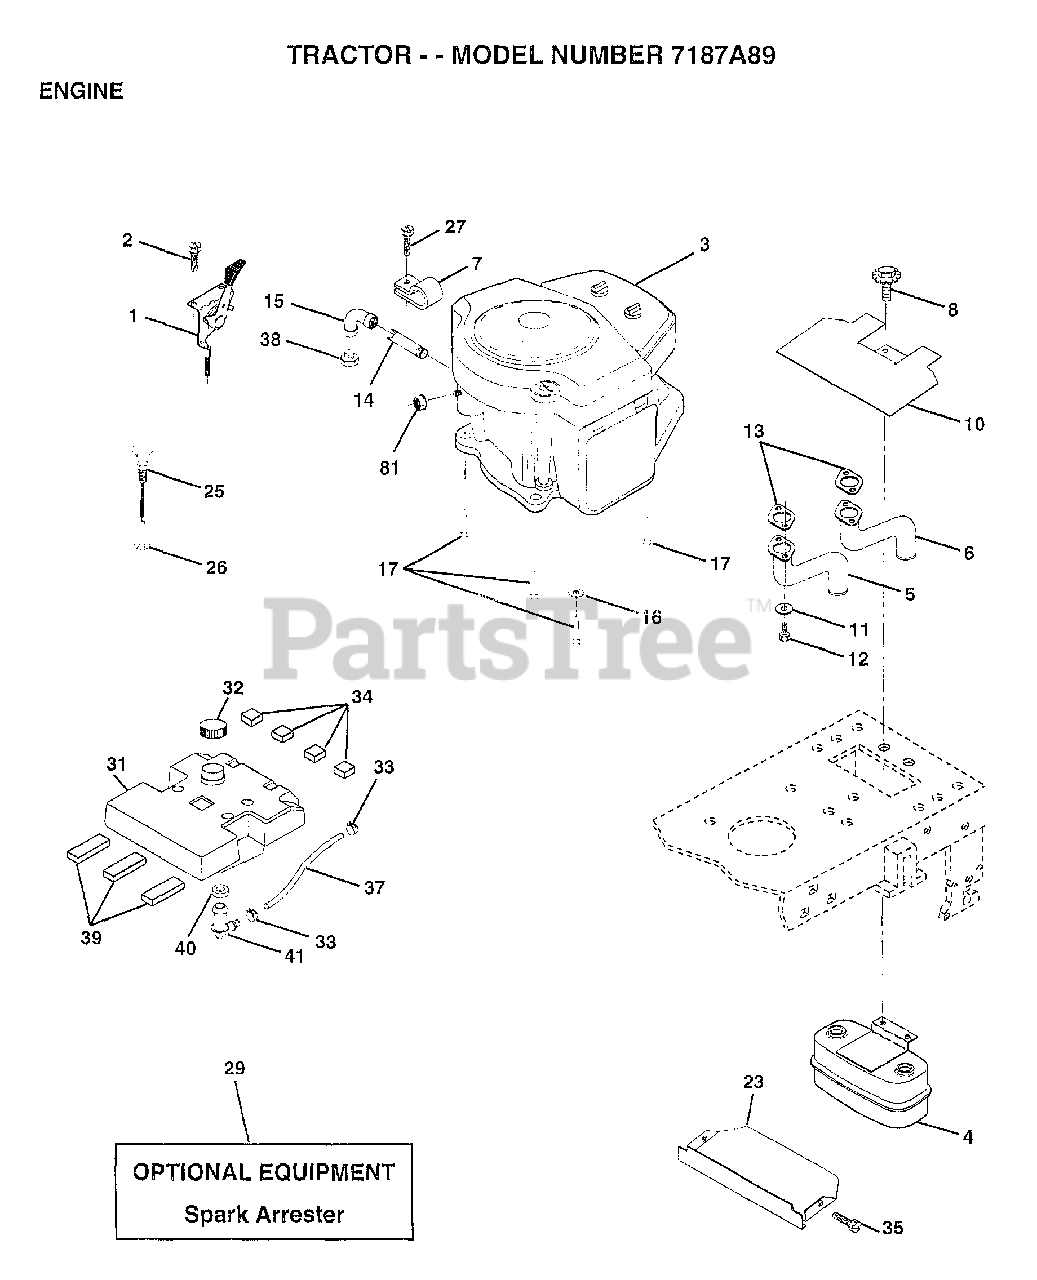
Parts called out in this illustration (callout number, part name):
1	CONTROL THROT. LH
2	SCREW LT
4	MUFFLER.TW.LOTONE
5	TUBE MANIFOLD LH
6	TUBE MANIFOLD RH
7	CLAMP.TUBE.DBL.EN
8	BOLT.5/16-18.UNC
10	SHIELD.HEAT.
11	LOCKWASHER
12	SCREW
13	GASKET MUFFLER
14	PIPE NIPPLE LT
15	ELBOW
16	LOCKWASHER
17	SCREW LT
23	SHIELD.BRN/DBR.GD
25	CONTROL.CHOKE.37
26	"NUT,KEPS 3/8-24IM"
27	"SCREW-TT,10-32 FL"
31	"TANK.FUEL,3.5 GAL"
32	CAP ASM FUEL
33	HOSE CLAMP
34	PAD-SPACER LT
35	SCREW
37	FUEL LINE T
39	PAD IDLER TI
40	BUSHING OUTLET T
41	STEM.TANK.FUEL
81	NUT
